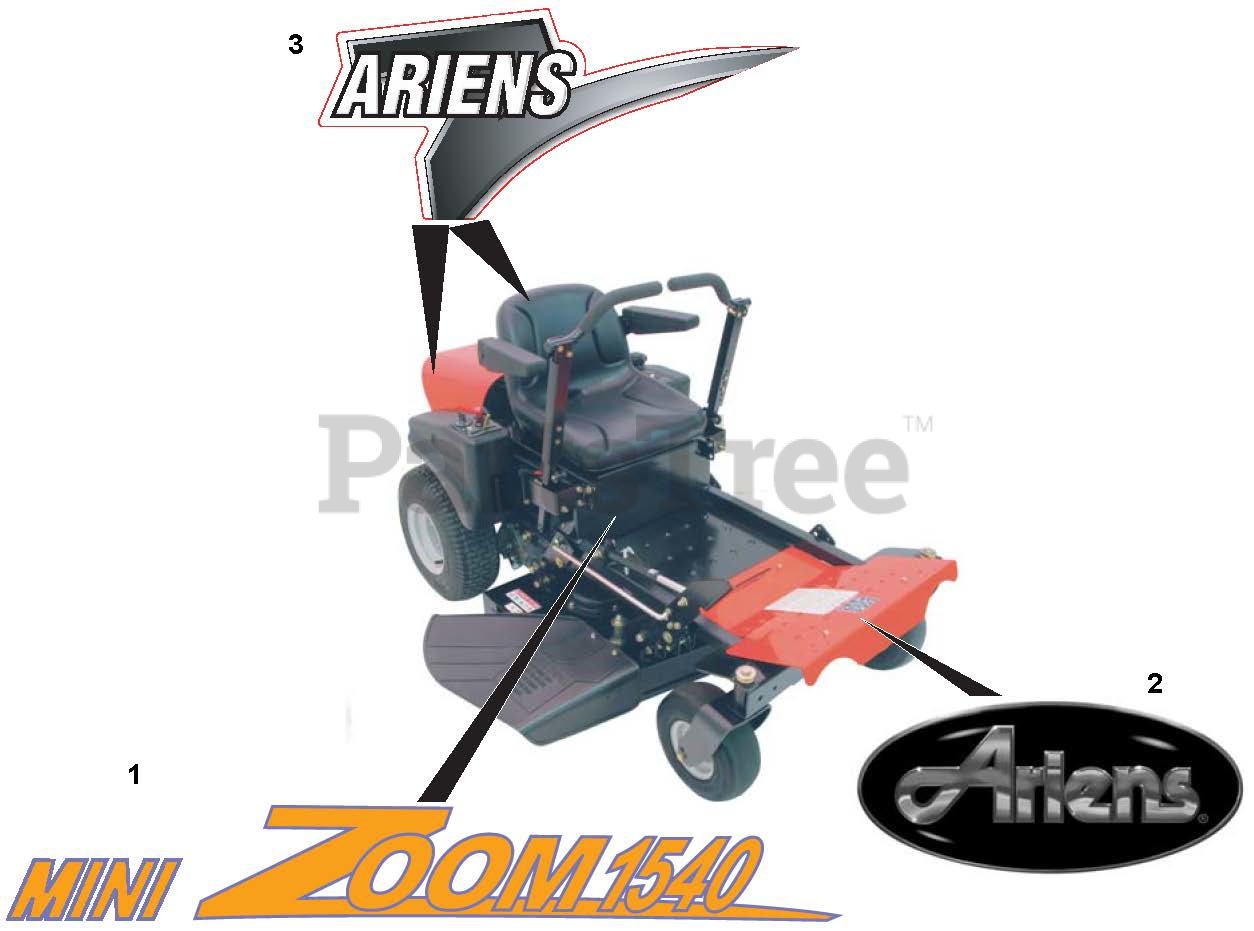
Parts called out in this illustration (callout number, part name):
1	DECAL,1434 MINI-ZOOM
1	DECAL,1540 MINI-ZOOM
1	DECAL,1534 MINI-ZOOM
2	DECAL-ARIENS JEWEL
3	DECAL,MINI-ZOOM HOOD
